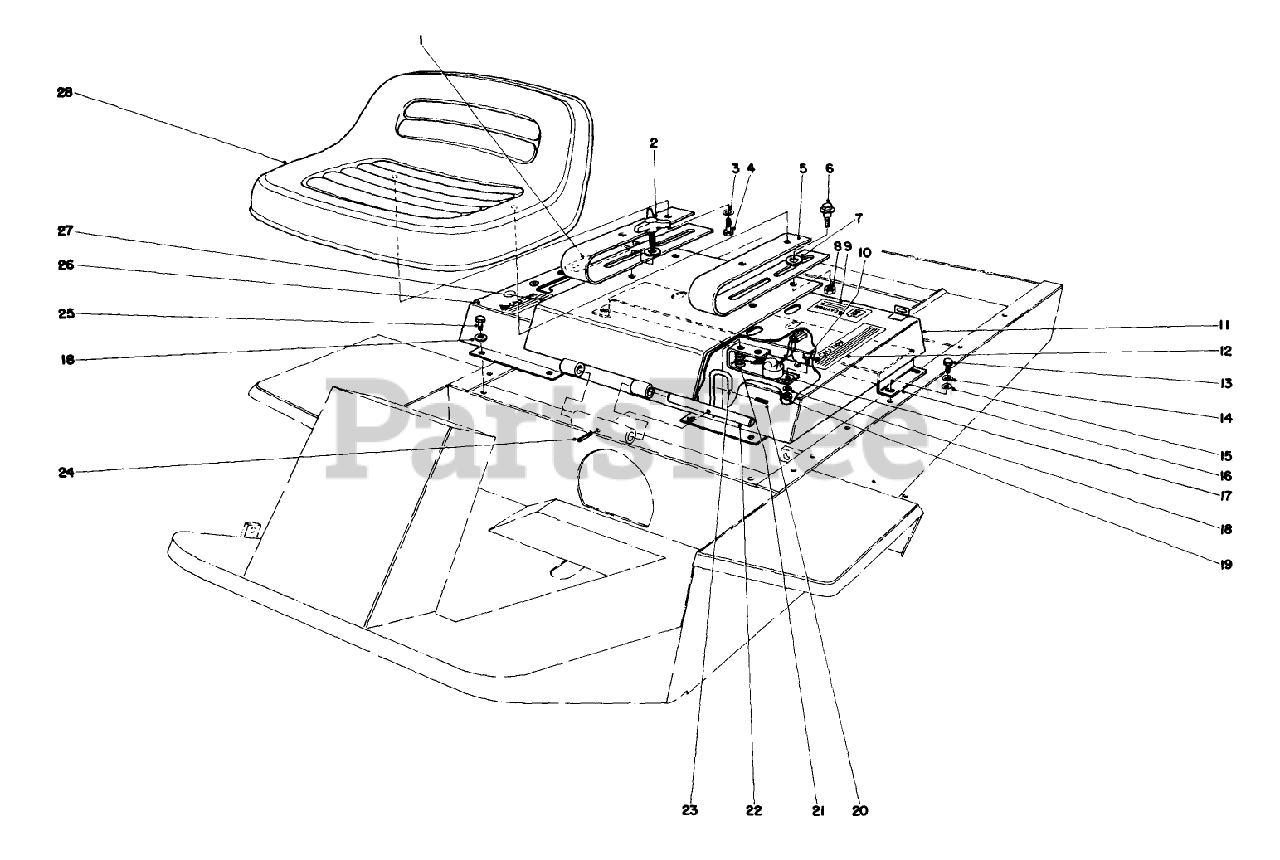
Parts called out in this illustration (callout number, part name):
1	Decal Caution
2	KNOB-SEAT
3	WASHER-LOCK
4	SCREW-HH
5	Seat Spring
6	BOLT-SHOULDER
7	WASHER-FLAT
8	NUT-LOCK, NI
9	DECAL-REFUELING
10	SCREW-HH
11	Cover-Seat Support
12	Decal Caution
13	SCREW-HH, TAP
14	WASHER-LOCK
15	WASHER-FLAT
16	Seat Support
17	SEAT SWITCH
18	WASHER-LOCK
19	NUT-HEX
20	PIN-SPRING
21	SPRING
22	SHAFT-PIVOT, SEAT
23	Pin Seat Switch
24	PIN-ROLL, SLOTTED
25	SCREW THD 1/4 20 5/8
26	Decal-Hydraulic Lift
27	Seat Mount
